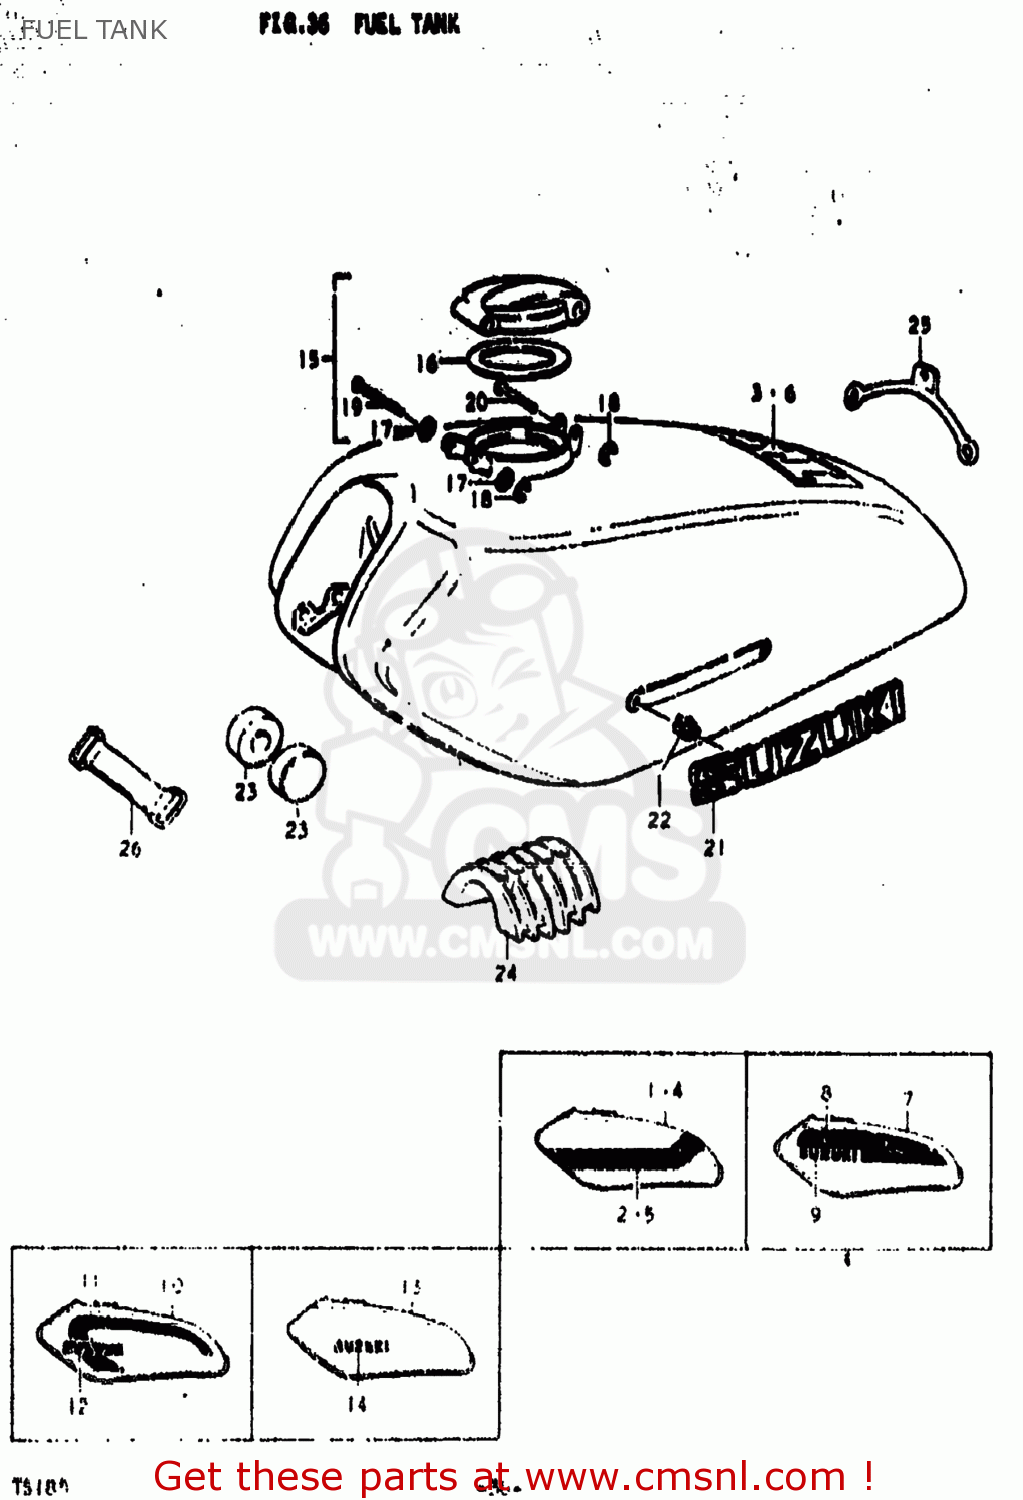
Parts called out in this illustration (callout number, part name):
1	TANK ASSEMBLY,FUEL
2	TAPE,FUEL TANK
4	TANK ASSEMBLY,FUEL
5	TAPE,FUEL TANK
7	TANK ASSEMBLY,FUEL
8	TAPE,FUEL TANK
9	EMBLEM
10	TANK ASSEMBLY,FUEL
11	TAPE,FUEL TANK
12	EMBLEM
13	TANK ASSEMBLY,FUEL
14	EMBLEM,FUEL TANK
15	CAP ASSEMBLY,FUEL TANK
16	GASKET (NAS)
17	WASHER
18	E RING
20	PIN,FUEL TANK C
21	EMBLEM
22	NUT
23	CUSHION
24	CUSHION
25	BAND
26	BAND
